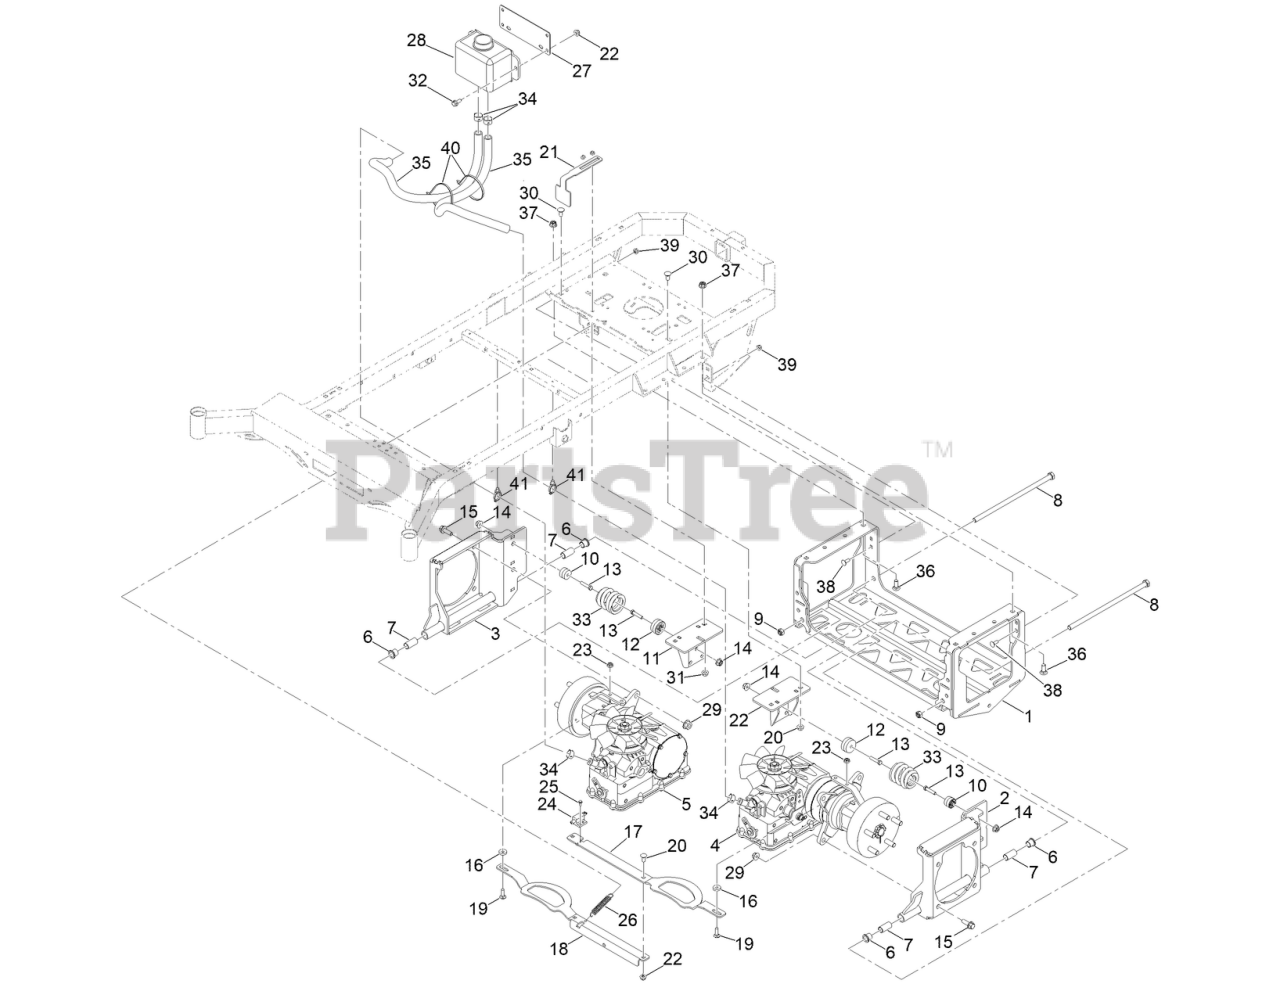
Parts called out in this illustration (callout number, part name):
1	HYDRO FRAME ASM
2	XD LT RR SUSP ASSY PAINTED
3	XD RT RR SUSP ASSY PAINTED
4	HTG16 LT SIDE TRANSM W/CONTROL ORIFICE
5	HTG16 PARKER RT SD TRANS W/CNTRL ORIFICE
6	BUSHING-FLANGE
7	.625 ID X .750 OD X 1.500IN OI BUSHING
8	5/8-11 X 15IN HEX C/S GR 2 ZC 3IN THD L
9	5/8-11 NYLON INSERT FLANGE L/NUT ZINC
10	SUSP SPRING OUTSIDE GUIDE
11	MWR SUSP FRAME BRKT ASSY PAINT
12	SUSP SPRING INSIDE GUIDE
13	3/8-16 X 1-3/4 HEX C/S GR 2 ZINC
14	3/8-16 NYLON INSERT FLANGE L/NUT YZ
15	SCREW-HHF
16	.312 ID X .875OD X .1875 THK F/W NYL
17	2022 XD PARK BRAKE BRKT G16 LT GREY
18	2022 XD PARK BRAKE BRKT G16 RT GREY
19	BOLT-CARR
20	BOLT-CARR
21	STAND TRANS BRAKE INTERLOCK BRKT PAINT
22	NUT-HF, NI
23	5/16-18 NYLON INSERT FLANGE L/NUT ZC
24	NO PLUNGER LIMIT SWITCH
25	8-32 X 1/2 IND. HWH SLOT TYPE F TCS ZINC
26	MWR BRAKE PEDAL RELEASE SPRING
27	MWR HYDRAULIC RESERVOIR MTG PLATE BLACK
28	HYDRAULIC FLUID RESERVOIR
29	NUT-HHF
30	SCREW-CARR
31	7/16-14 HEX FLANGE NUT W/SERR ZINC
32	SCREW-HHF
33	SRT RR SUSP SPRING
34	22MM HOSE CLAMP (CTB-22ST-FK)
35	MWR 5/8IN HYDRAULIC HOSE, 1FT
36	SCREW-CARR,PATCH
37	1/2-13 HEX FLANGE 2-WAY REV CNTR L/NYZ
38	3/8-16 X 1 CARRIAGE BOLT YZ GR.8
40	TIE-CABLE
41	CLIP-TIE
